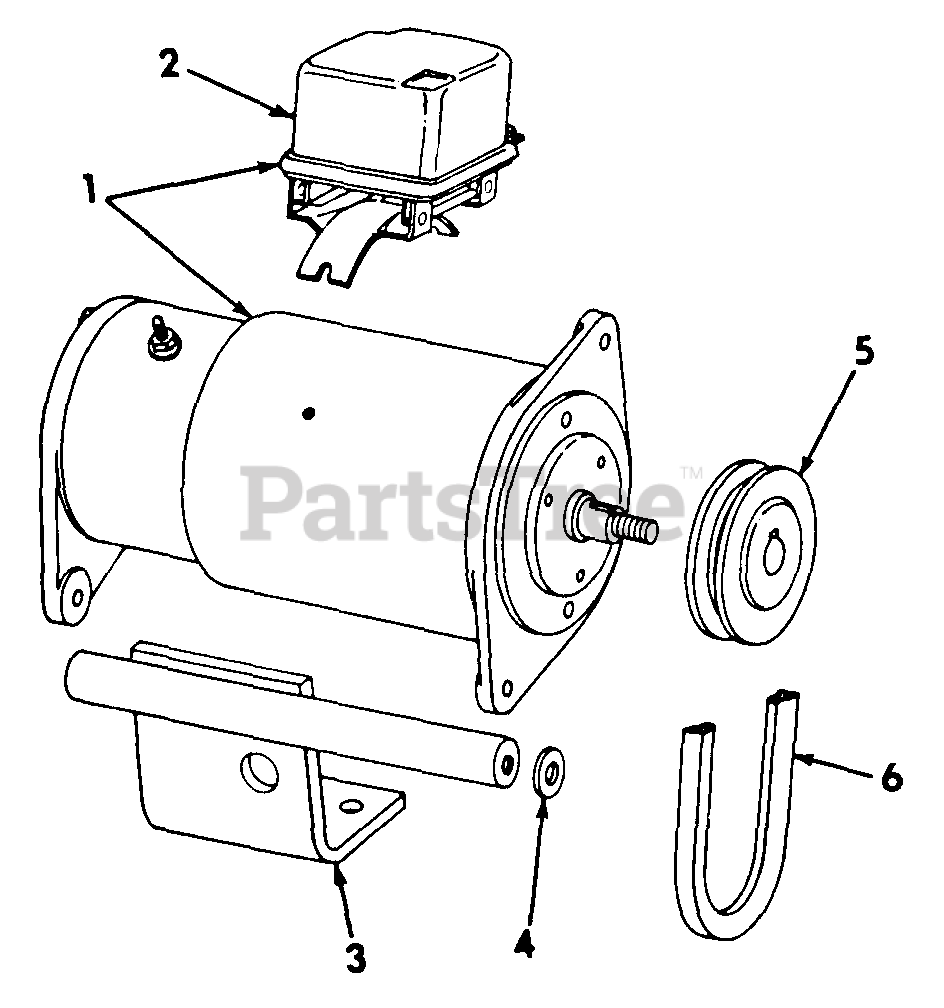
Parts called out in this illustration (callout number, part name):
1	MOTOR GENERATOR ASSY
2	REGULATOR ASSY, VOLTAGE
3	BRACKET ASSY. MOTOR GENERATOR
4	WASHER, 344 X 1.000 X 105 PLN
5	PULLEY, MOTOR GENERATOR
